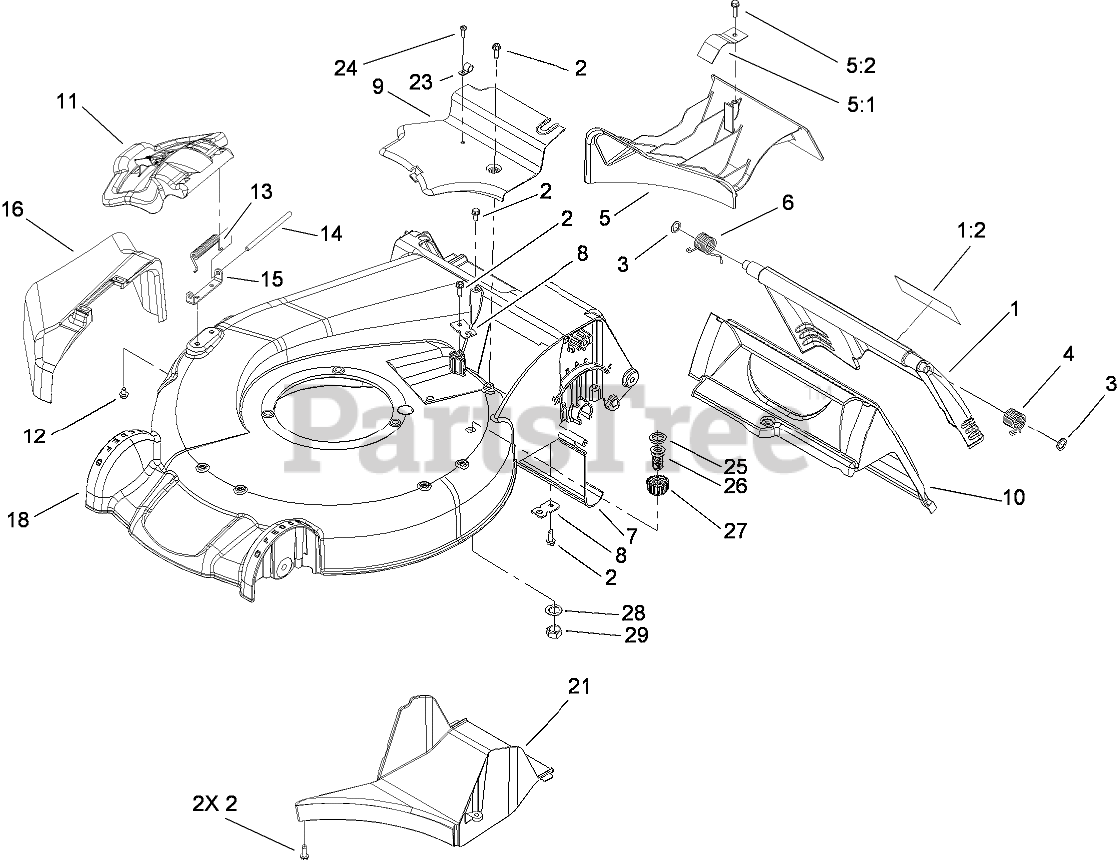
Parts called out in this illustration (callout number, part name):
1	REAR DOOR ASM
1:2	DECAL-WARNING
2	SCREW-HWHTF
3	WASHER-NYLON
4	SPRING-TORSION
5	PLUG-MULCH ASM
5:1	TAB-SPRING
5:2	SCREW-HWH
6	SPRING-TORSION
7	SHIELD-TRAILING
8	BRACKET-CABLE, TRACTION
9	COVER-BELT
11	DISCHARGE DOOR ASM
12	SCREW-HWH
13	SPRING-TORSION
14	ROD-COVER
15	BRACKET-COVER
16	CHUTE-DISCHARGE, SIDE
18	HOUSING ASM
21	TUNNEL-DISCHARGE
23	CLAMP
25	WASHER-SEAL, WASHOUT PORT
26	PORT-WASHOUT
27	COUPLING-HOSE, WASHOUT PORT
28	WASHER-TOOTH, INTERNAL
29	NUT-JAM
